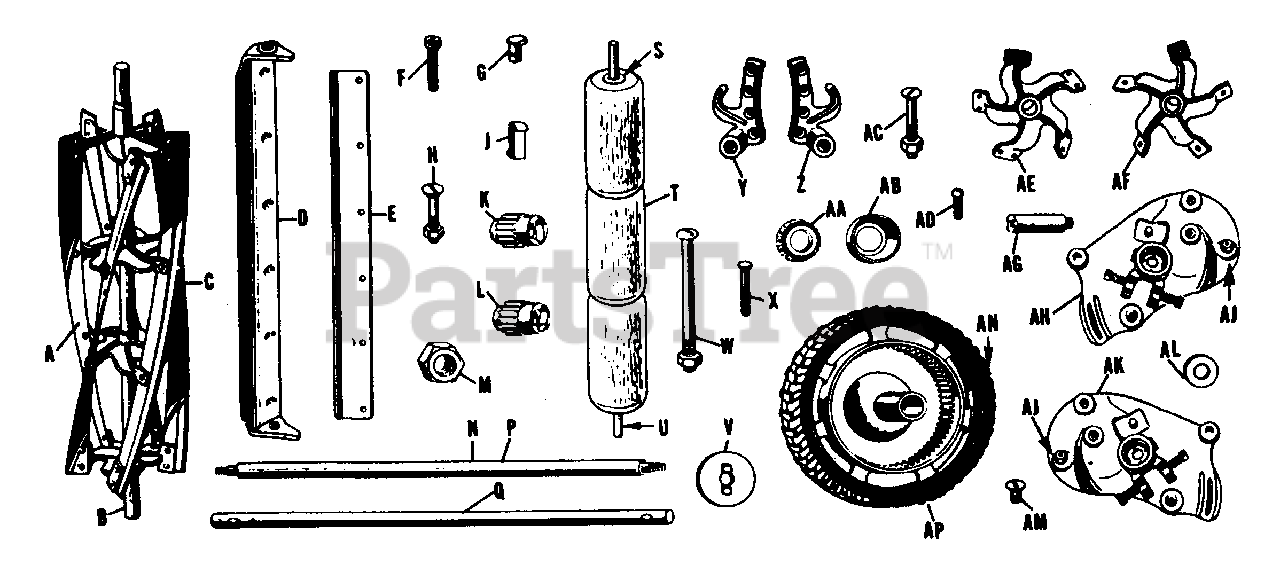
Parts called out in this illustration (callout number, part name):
A	Cylinder Knife 21"
B	Cylinder Shaft, 21", 11/16" dia x 26 1/8" lg.
C	CYLINDER ASSEMBLY, Less Bearings or Spacer
D	Cast Back, less Stationary blade 21"
D	Cast Back, complete with blade assembled
E	Steel Stationary Blade, 21"
F	SET SCREW, to Regulate Cast Back
G	Oil cup, for side plate
H	BOLT AND NUT, For Roller Bracket, 1/4" x 1-1/8"
J	Steel Pawl, 3/8" wide (both alike)
K	left Hand Pinion, 11/16" hole, 11 teeth
L	Right Hand Pinion, 11/16" hole, 11 teeth
M	Nut for end of front frame shaft
N	Front Frame Shaft
P	Rear Frame Shaft
Q	Cylinder Shaft, 21", 11/16" dia x 26 1/8" lg.
S	SPACING, Washer for sectional roller
T	Sectional Wood Roller 2-7/16" x 6-9/16" (1/2" hole)
U	Roller Shaft 21" (7/16" x 22-13/16")
V	Wheel Washer, for side plate (2 lugs)
W	Wheel Bolt and Nut 5/16" x 3 1/4"
X	SPRING LOCK PIN, To attatch cylinder end to cylinder shaft
Y	LEFT HAND ROLLER, Bracket
Z	RIGHT HAND ROLLER, Bracket
AA	Precision Taper Cylinder Bearing
AB	BEARING CUP, For side plate (less bearings)
AC	Cast Back Bolt and Nut
AD	RIVETS, For cylinder knives (1 set)
AE	Cylinder End (both alike)
AF	Cylinder Rings (all alike)
AG	Steel Wheel Stud 7/8" x 2-25/32"
AH	Left Hand Side Plate with stud
AJ	BOLT AND NUT, For tow bracket
AK	Right Hand Side Plate with stud
AL	FLAT WASHING, For roller bracket bolt and side plate towing bolt
AM	Machine screw for stationary blade, 1/4" x 3/8" flat head
AN	RUBBER TIRE, 3" Wide for Wheel 2645-W
AP	WHEEL, With tire PM-51-WW-D assembled
AP	Wheel only, less tire
